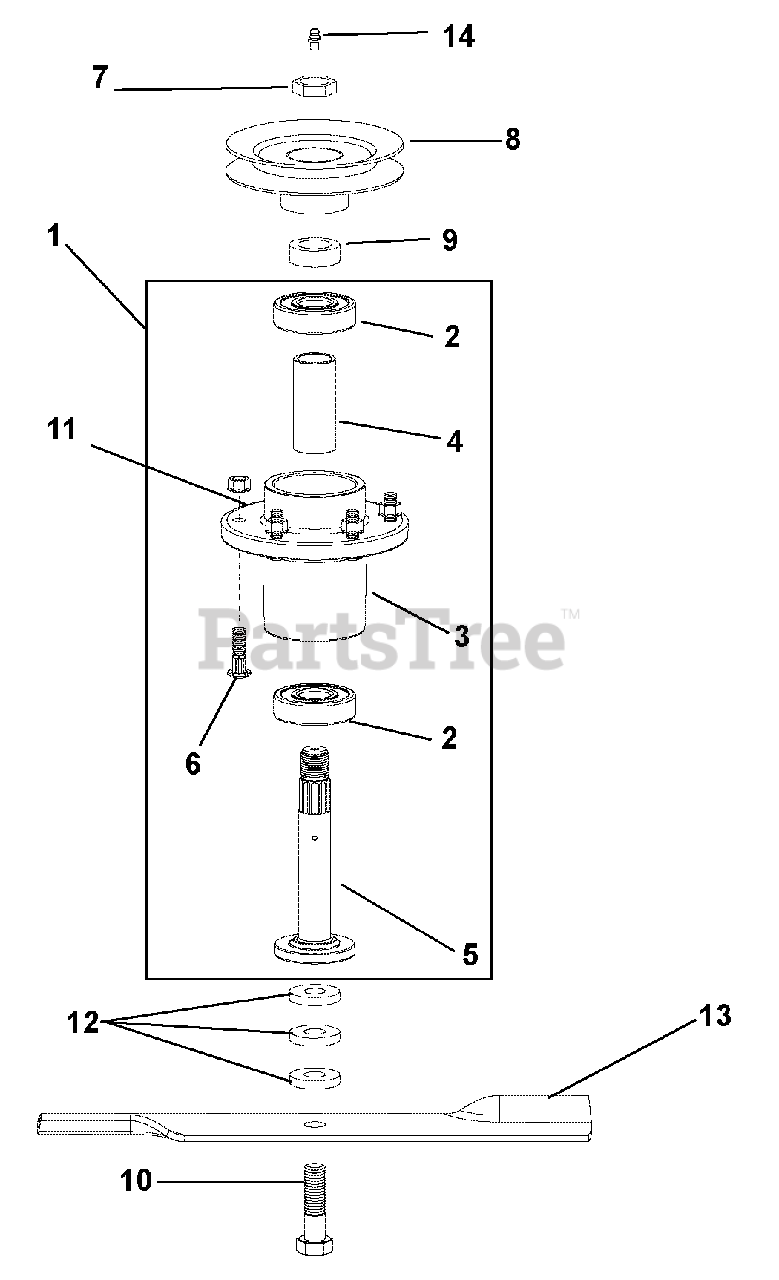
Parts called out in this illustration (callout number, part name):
1	Spindle Assembly, Includes Items 2, 3, 4, 5, 6, 14
2	Ball Bearing
3	Housing
4	Spacer, 1.000 x 1.250 x 2.772
5	Shaft, Spindle
6	Bolt, 3/8 x 1.25 RIB
7	Nut, Pulley (Special)
8	Pulley, Cutter Housing (994100)
9	Spacer, Pulley
10	Bolt, Hex .62-11 x 2.25
11	Nut, Hex .31-18
12	Spacer, Blade Bolt
13	16.5" Blade (994100)
14	Zerk, Grease S/O
